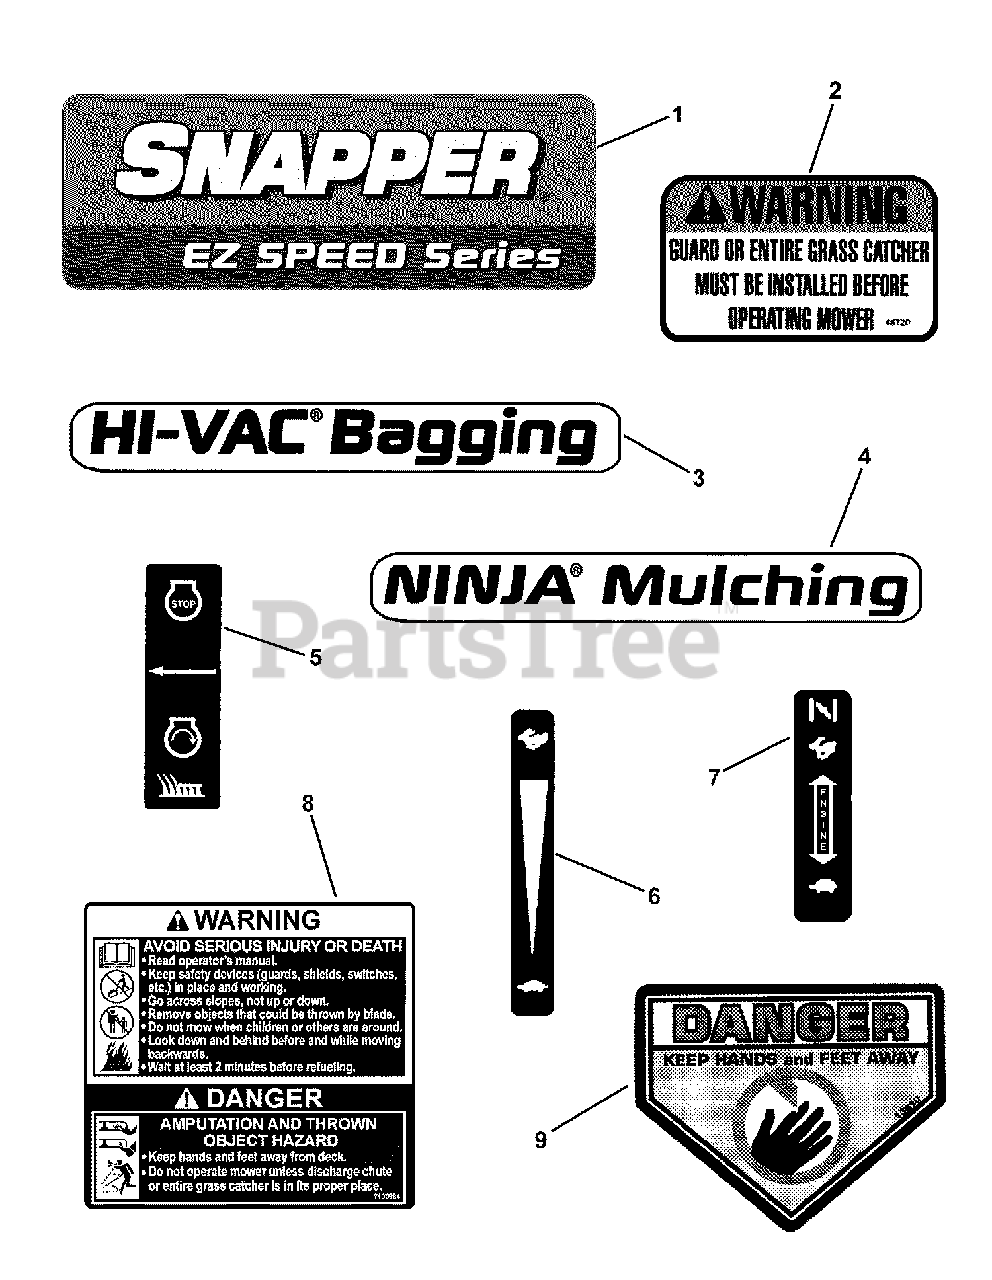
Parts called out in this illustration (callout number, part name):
1	DECAL, Easy Speed, Control Panel
2	DECAL, Chute/Deflector
3	DECAL, Front Cover, Hi-Vac
4	DECAL, Front Cover, Ninja Mulching System
5	DECAL, OPC Bail (International Symbol)
6	DECAL, Speed Shift
7	DECAL, Throttle Control, KWV
8	DECAL, Warning/Danger Walk-Behind Mowers
9	DECAL, Danger, Cut Finger
